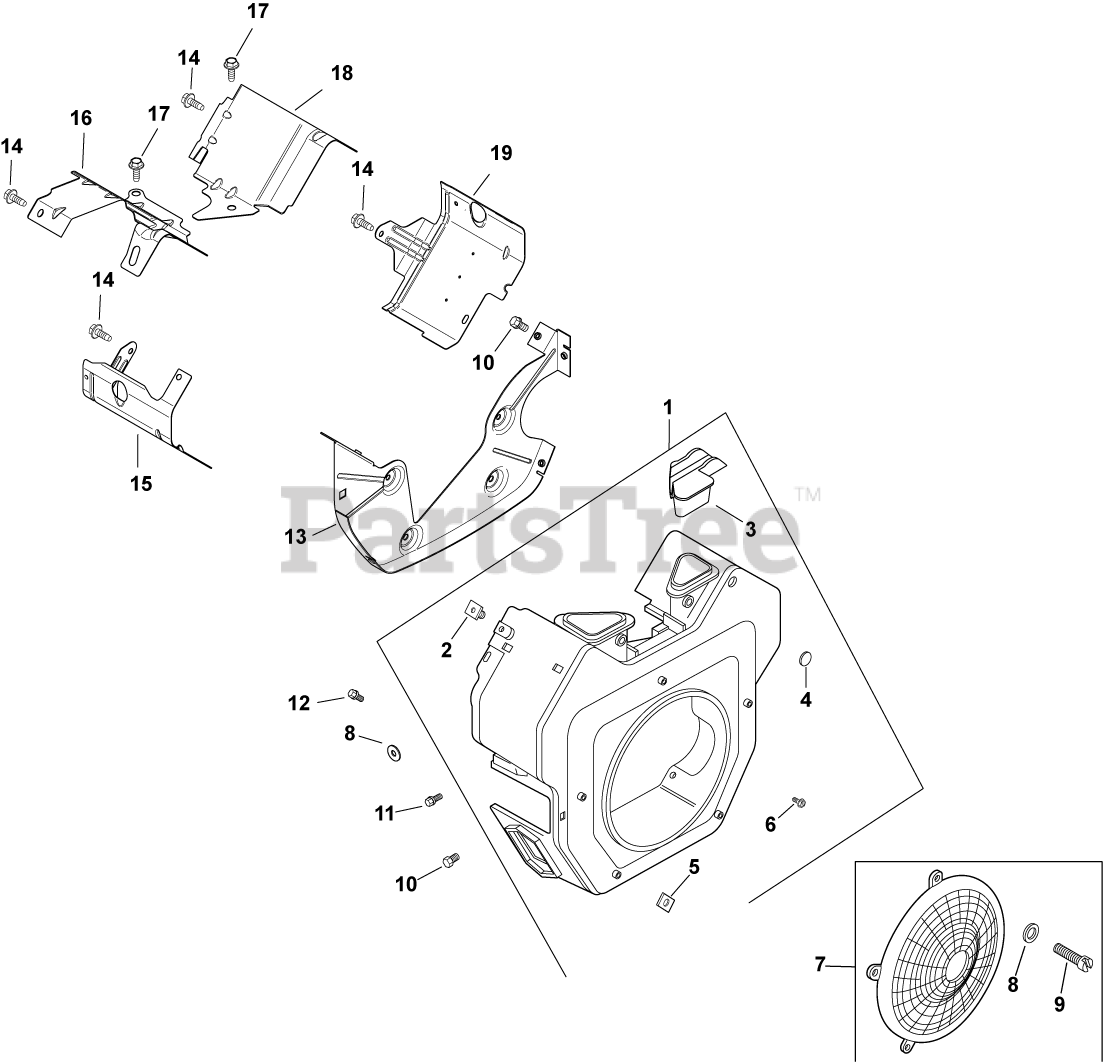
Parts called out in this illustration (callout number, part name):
1	KIT, BLOWER HOUSING ASSY-(#24027492S)
2	NUT, PLASTIC
3	COVER, BLOWER HOUSING-USE 24 096 119-S
4	PLUG, BUTTON 9/16
5	NUT, PLASTIC (KM)-USE 25 100 37-S
6	SCREW, WSH HD TAP #8-18X1/2"
7	KIT, FIXED GUARD
8	WASHER, FLAT 7/32"
9	SCREW, LBD SCKT PAN M5X0.8X10
10	SCREW,FLG THD FRM M6X1.0X16-(#25086397S)
11	SCREW - USE M-545016-S
12	SCREW,FLG THD FRM M5X0.8X16-(#25086398S)
13	PLATE, BACKING-USE 24 146 59-S
14	SCREW, FLG THD FRM M5X.8X20-(#25086399S)
15	BAFFLE, LEFT BARREL -USE 24 063 88-S
16	BAFFLE, VALLEY #2 SIDE-USE 24 063 94-S
17	SCREW, FLG THD FRM M5X.8X10
18	BAFFLE, VALLEY (CH)-USE 24 063 93-S
19	BAFFLE, RIGHT BARREL-USE 24 063 85-S
